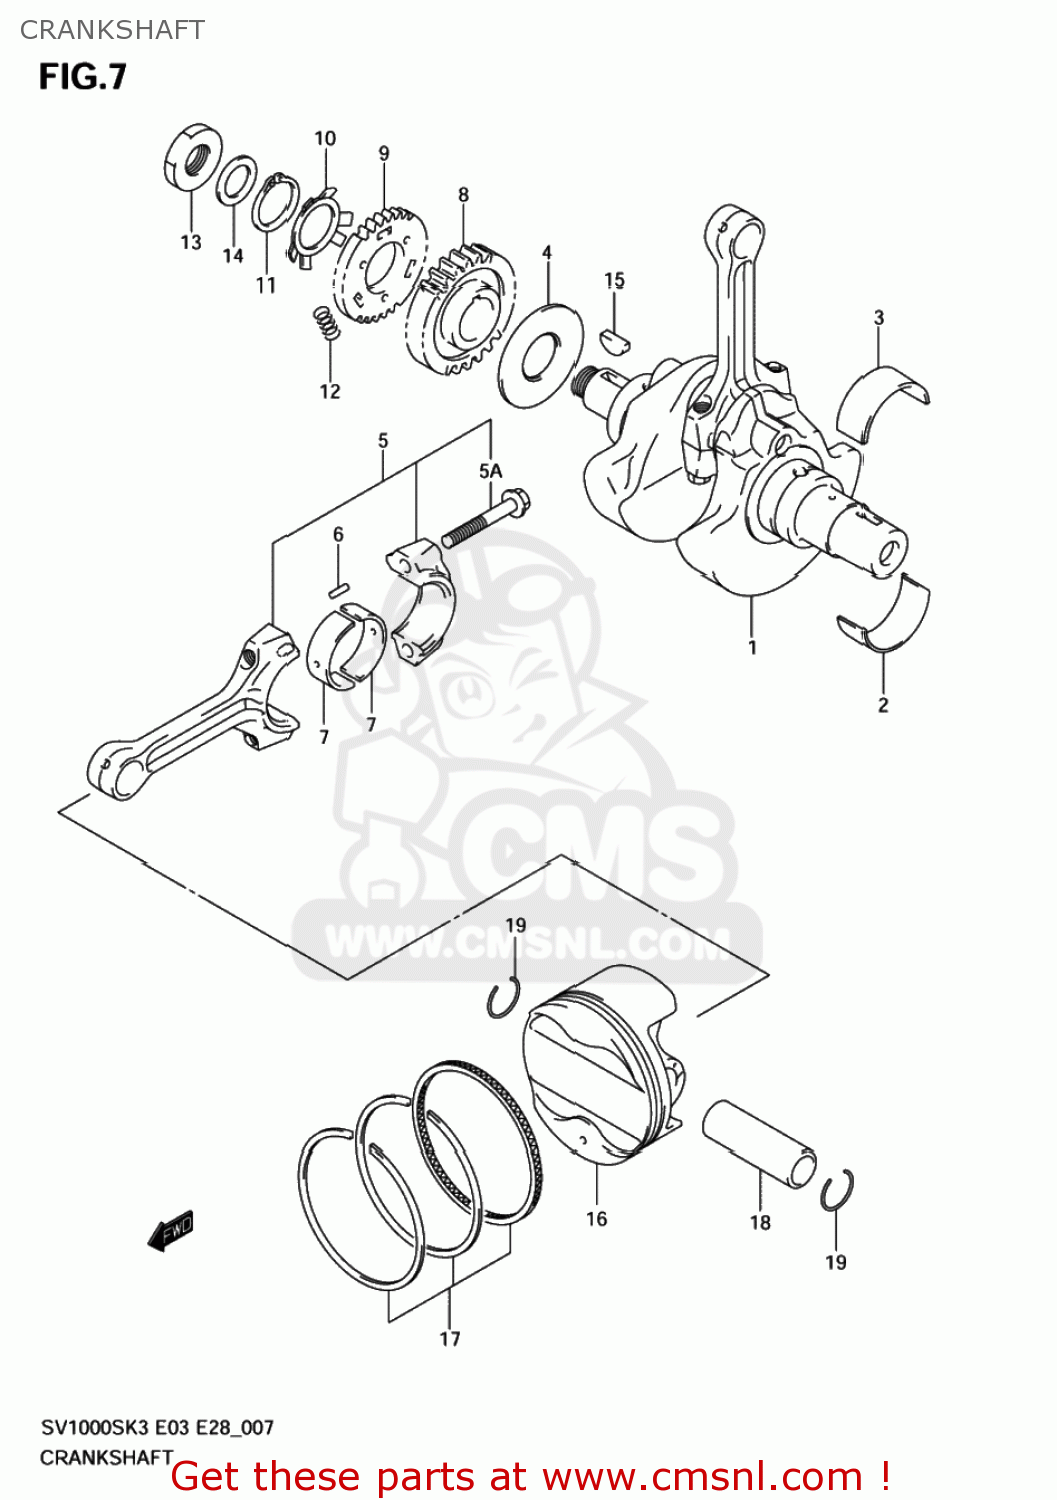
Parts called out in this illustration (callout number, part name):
1	CRANKSHAFT
2	BEARING,CRANKS
3	BEARING,CRANKS
4	WASHER,CRANK THRUST
5	CONNECTING ROD ASSY
5A	BOLT,CONNECTING ROD
6	PIN,CONNECTING ROD
7	BEARING,CRANK PIN
8	GEAR,PRIMARY DRIVE
9	GEAR,PRIMARY DRIVE SCISSORS
10	WASHER,PRI DRIVE
11	CIRCLIP
12	SPRING
13	NUT
14	WASHER
15	KEY
16	PISTON
17	RING SET,PISTON
18	PIN,PISTON
19	CIRCLIP
